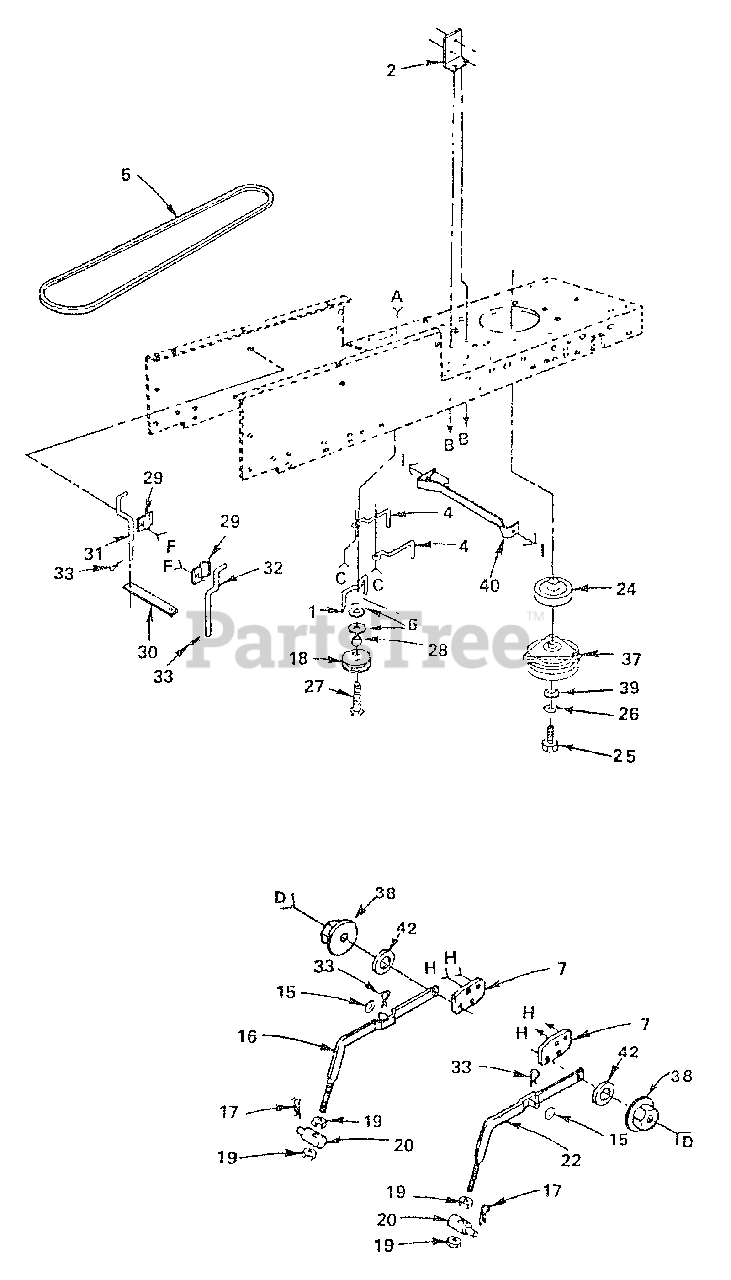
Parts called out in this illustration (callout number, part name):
1	Retainer Belt
2	Bracket- Switch
4	Keeper- Belt, Engine
5	V-Belt, Drive
6	Washer 13/32 x 13/16 x 12 Ga.
7	Bracket - Suspension
15	Washer 17/32 x 15/16 x 16 Ga.
16	Arm Assembly - Suspension, L.H.
17	Retainer - Spring
18	Idler - Flat
19	Nut - Hex 1/2-13
20	Trunnion - Lift, Lower
22	Arm Assembly - Suspension, R.H.
24	Pulley- Engine
25	Bolt - Hex 7/16-20 x 4
26	Washer- Lock 7/16
27	Bolt - Hex 3/8-16 x 2 - 3/4
28	Spacer
30	Strap - Locator
31	Keeper - Belt, L. H.
32	Keeper - Belt, R. H.
33	Spring - Retainer
37	Clutch - Electric
38	Centerlock Flange Nut - 3/8-16
39	Washer - 15/32 x 1-3/8 x 1/4
40	Locator - Clutch
42	Spring Washer
